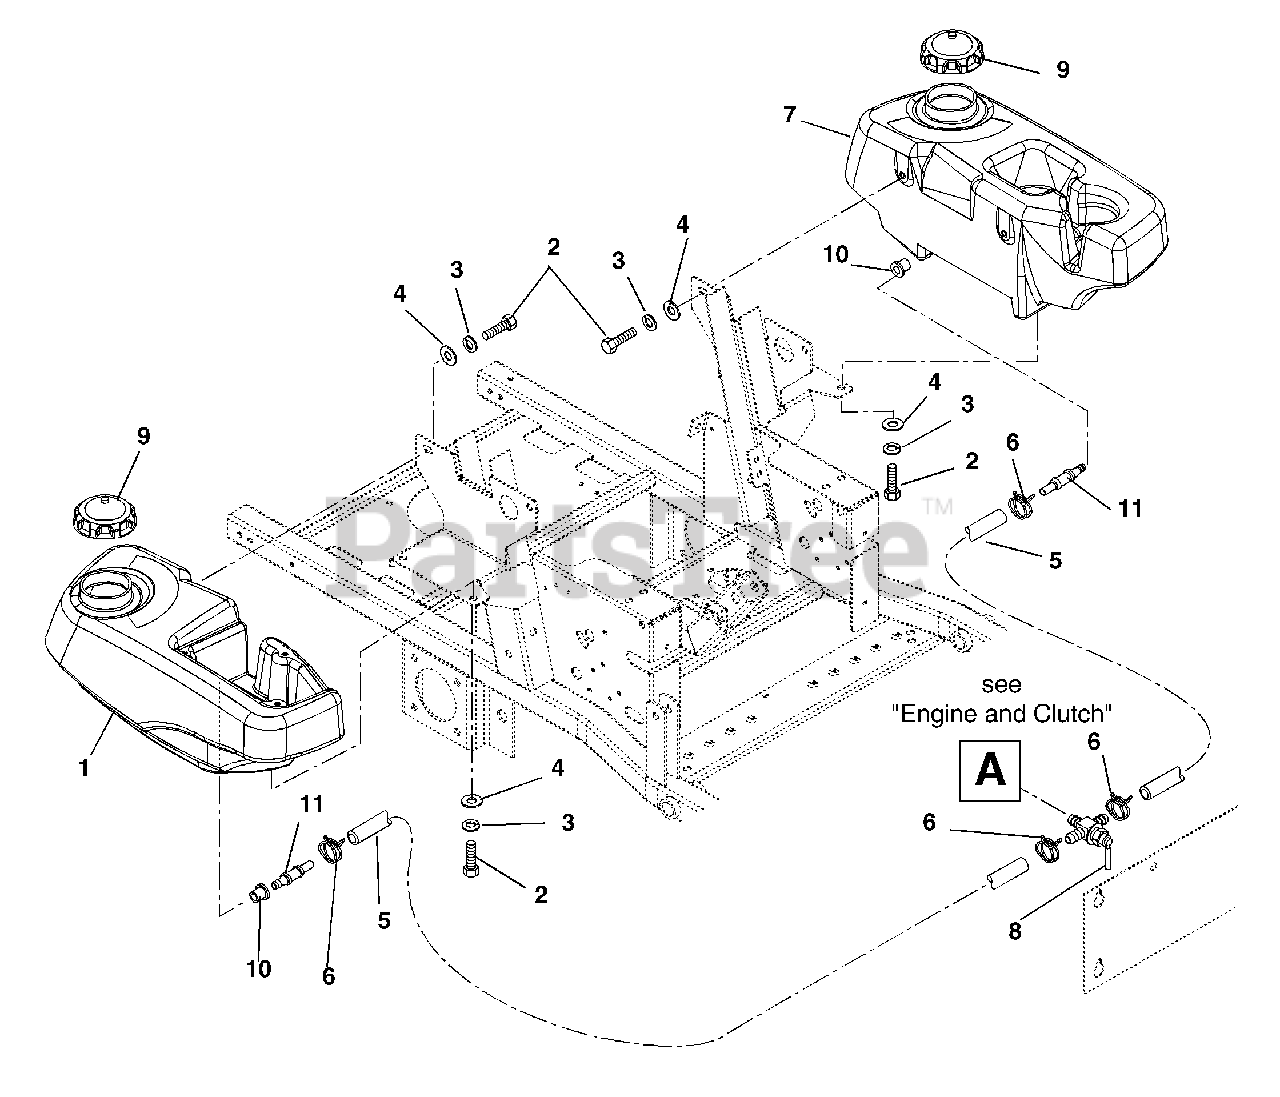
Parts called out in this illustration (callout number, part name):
1	Fuel Tank Right-Hand
2	Bolt-Hex .31-18 x .75 Grade 5
3	Washer-Locking .31 x .078
4	Washer-Flat-Steel .38 x .875 x .083
5	Gas Line-Bulk 1/4" ID
6	Hose-Clamp
7	Fuel Tank Left-Hand
8	Valve, Fuel
9	Cap-Gas
11	Fuel Tank Fitting
